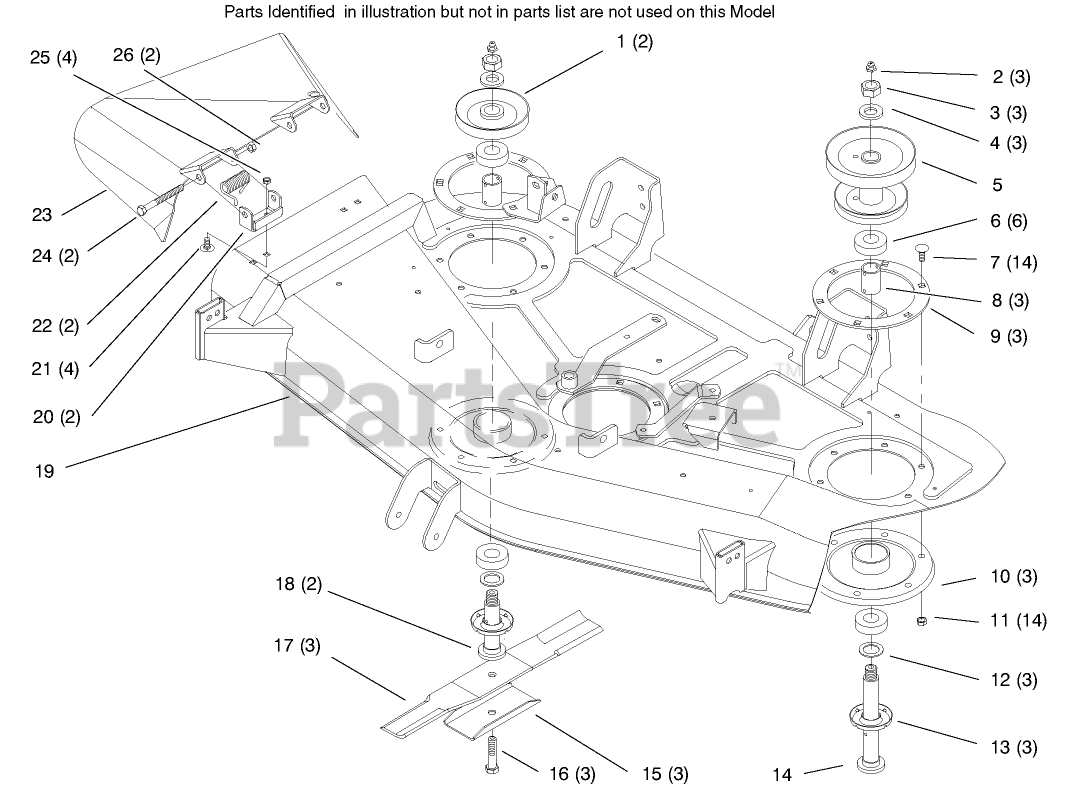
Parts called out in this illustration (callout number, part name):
1	PULLEY
2	FITTING-GREASE
3	NUT-JAM
4	WASHER-FLAT
5	PULLEY-DOUBLE
6	BEARING-BALL
7	SCREW-CARR
8	SPACER-BEARING
9	RING-DECK SUPPORT
11	NUT-HF
12	WASHER-BACKUP
13	SHIELD-BEARING
14	SHAFT - SPINDLE
15	STIFFENER-BLADE
16	SCREW-BLADE
18	SHAFT-SPINDLE
20	BRACKET-PIVOT
21	SCREW-CARR
22	SPRING
23	DEFLECTOR/DECAL ASM-INTL
24	SCREW-HH
25	NUT-LOCK, NI
26	NUT-HEX
